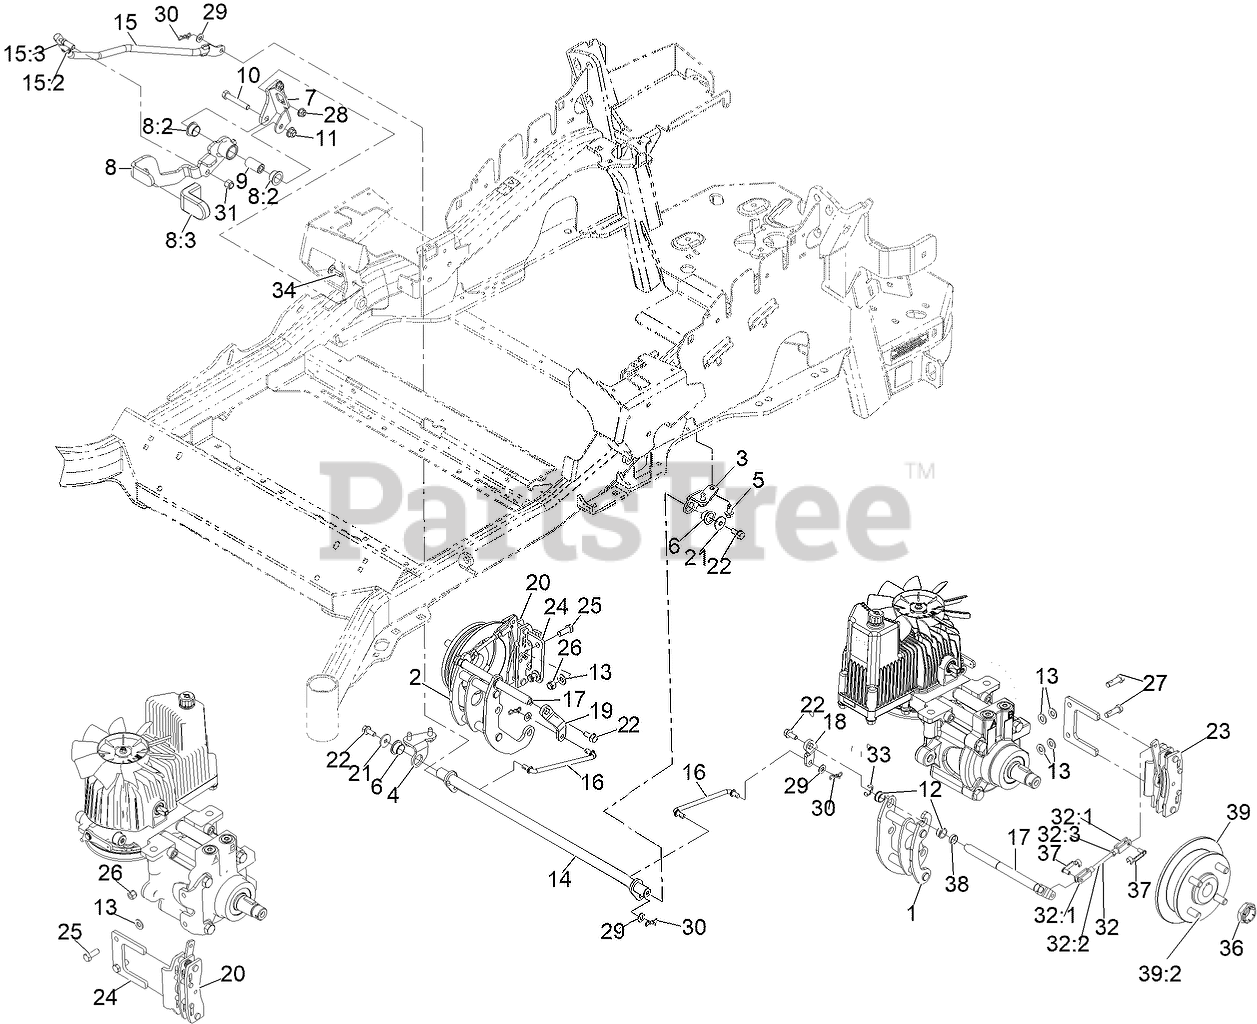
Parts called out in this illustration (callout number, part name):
1	MOUNT-BELLCRANK, LH
2	MOUNT-BELLCRANK, RH
3	MOUNT-PIVOT, LH
4	MOUNT-PIVOT, RH
5	Screw-HWH 5/16-18 X 3/4 Tf
6	BUSHING-FLANGE
7	BRACKET-MOUNT
8	BRAKE LEVER ASM W/GRIP M-R
8:2	BUSHING-FLANGE
8:3	GRIP-LEVER
9	HANDLE-PIVOT, BRAKE
10	SCREW-HH
11	NUT-HF, NI
12	BUSHING
13	WASHER-FLAT
14	Shaft-Cross
15	ASM, Front Linkage
15:2	END-TIE ROD, RH
15:3	NUT-HJ
16	Link-Mid
17	BELLCRANK
18	ARM-INNER, LH
19	ARM-INNER, RH
20	Caliper-Brake, RH
21	WASHER-FLAT
22	SCREW-HHF
23	Caliper-Brake, LH
24	PLATE-MOUNT, BRAKE
25	SCREW-HH,
26	NUT-LOCK
27	Screw-HH, Patch
28	NUT-HF, NI
29	WASHER-PLAIN
30	PIN-COTTER, LOCKING
31	NUT-LOCK
32	REAR LINKAGE ASM
32:3	NUT-JAM
34	BOLT-CARR
36	LOCKNUT
37	PIN-CLEVIS, SPRING
39	Wheel Hub ASM
39:2	STUD-WHEEL
